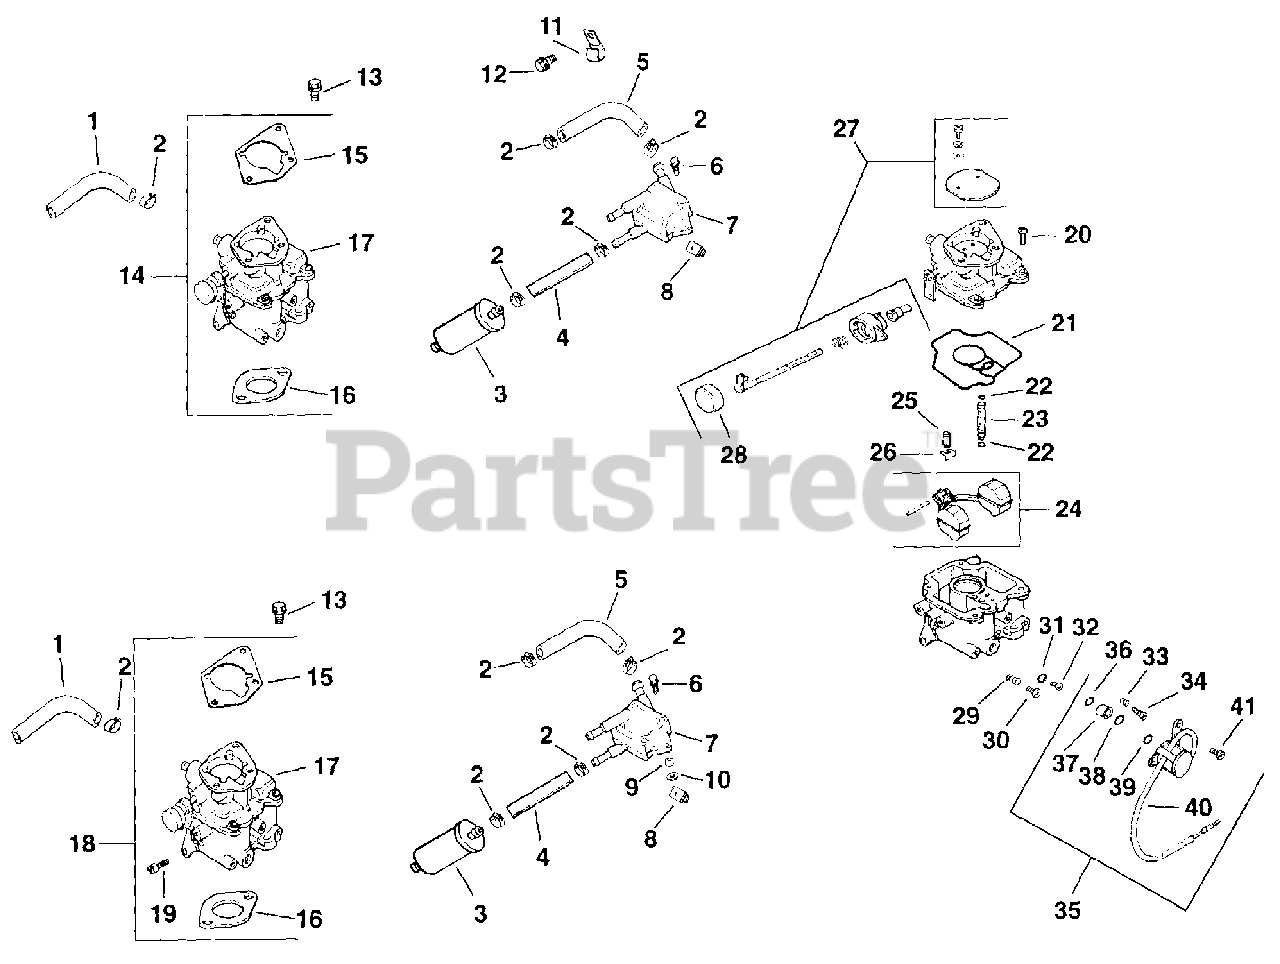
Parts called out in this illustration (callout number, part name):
2	CLAMP, HOSE 1/2" USE 25 237 14-S
4	LINE FLEXBLE FUEL (3.5" x.25") -USE 25 1
6	SCREW, TAP M6X1.7X18
7	PUMP, FUEL - PULSE - USE 24 393 16
8	NUT, PLASTIC (KM)-USE 25 100 37-S
11	CLIP, CABLE
12	SCREW - USE M-650012
13	SCREW - USE M-651030
15	GASKET, AIR CLEANER BASE
16	GASKET, CARBURETOR
17	Carburetor assembly
18	CARBURETOR - USE 24 853 35
18	KIT, CARBURETOR W/GASKETS-KSF
19	SCREW - DISCONTINUED
20	SCREW, CARBURETOR BODY
21	GASKET, CARBURETOR BODY
22	O-RING, SLOW JET
23	JET, SLOW
24	KIT, REPAIR FLOAT
25	VALVE, INLET NEEDLE
26	CLIP, INLET NEEDLE VALVE
27	KIT, REPAIR CHOKE
28	CAP, CHOKE LEVER
29	SPRING, IDLE SPEED ADJ SCREW
30	SCREW, IDLE
31	O-RING, MAIN JET SCREW
32	JET, MAIN
33	SPRING, IDLE NEEDLE
34	NEEDLE, IDLE
35	KIT, SOLENOID
36	O-RING, SOLENOID
37	SEAT, SOLENOID
38	O-RING, SOLENOID
39	O-RING, SOLENOID
40	SOLENOID ASSEMBLY
41	SCREW, SOLENOID
